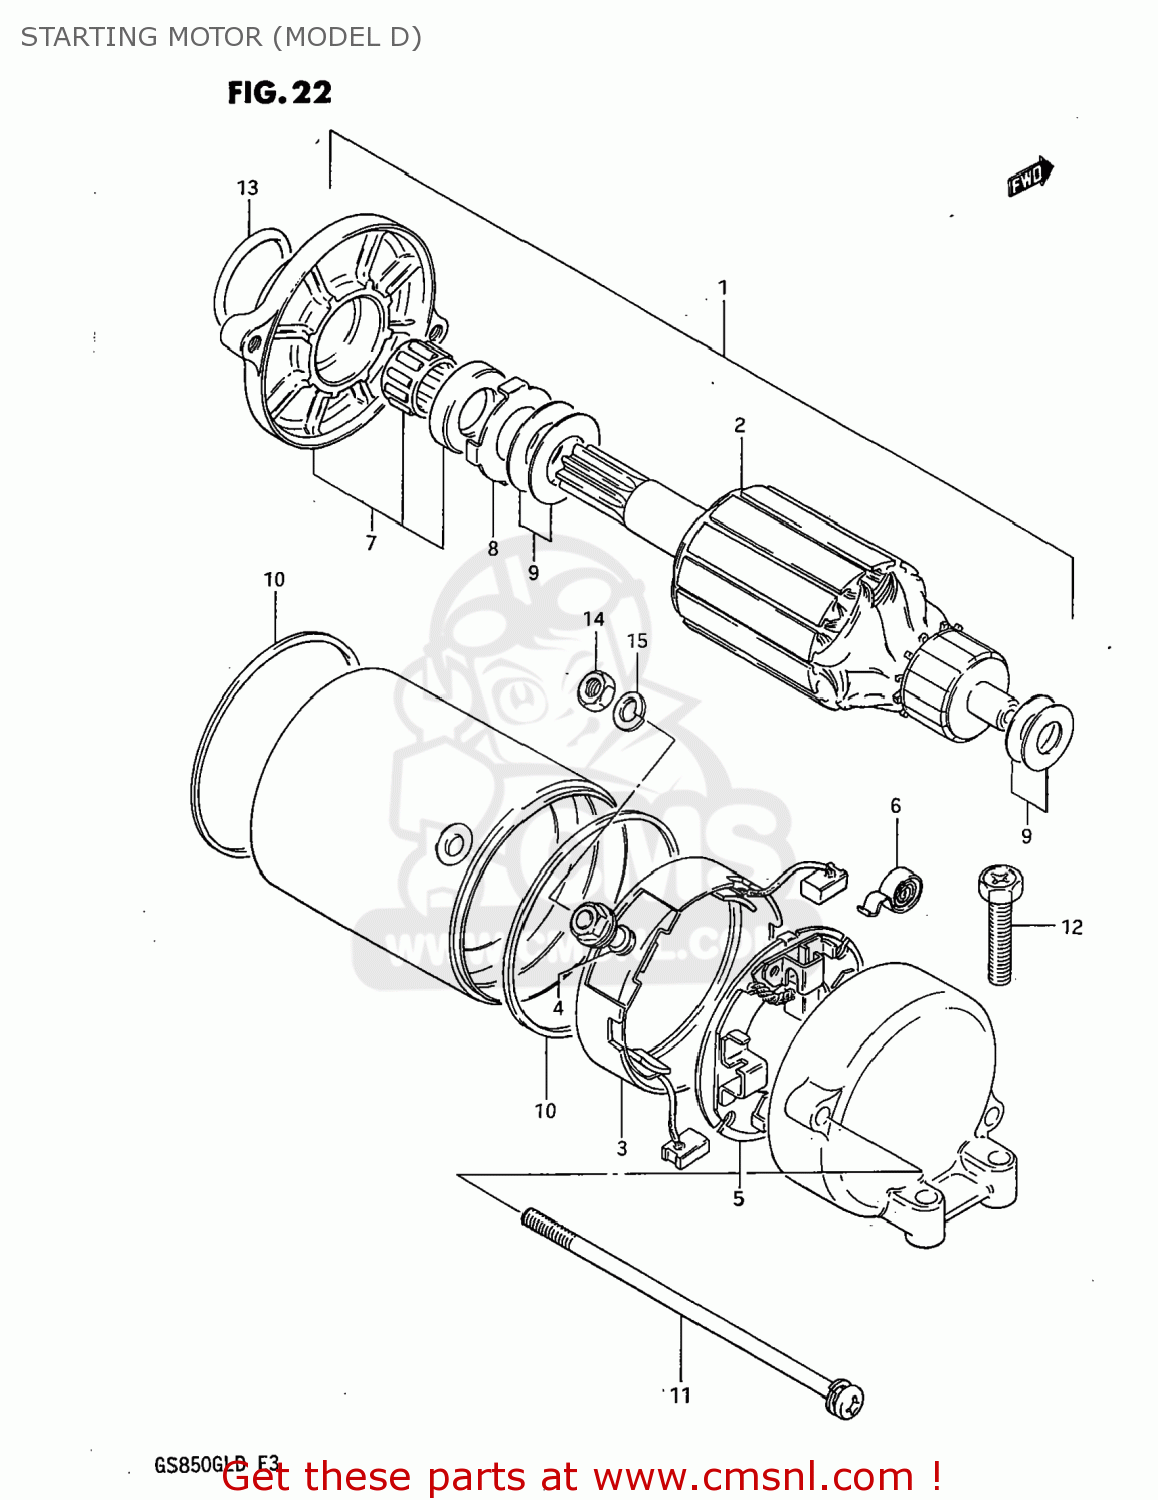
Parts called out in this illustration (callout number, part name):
1	MOTOR ASSEMBLY,STARTING
2	ARMATURE
3	BRUSH TERMINAL SET (+)
4	O RING
5	HOLDER,BRUSH
6	SPRING,BRUSH
7	HOUSING SET,STARTING MOTOR
8	SHIM SET
9	SHIM SET
10	SEAL,RING
11	BOLT,STARTING MOTOR HOUSING
12	SCREW (6X25)
13	O RING(D:2,ID:24.5)
14	NUT 6MM
15	LOCK WASHER
